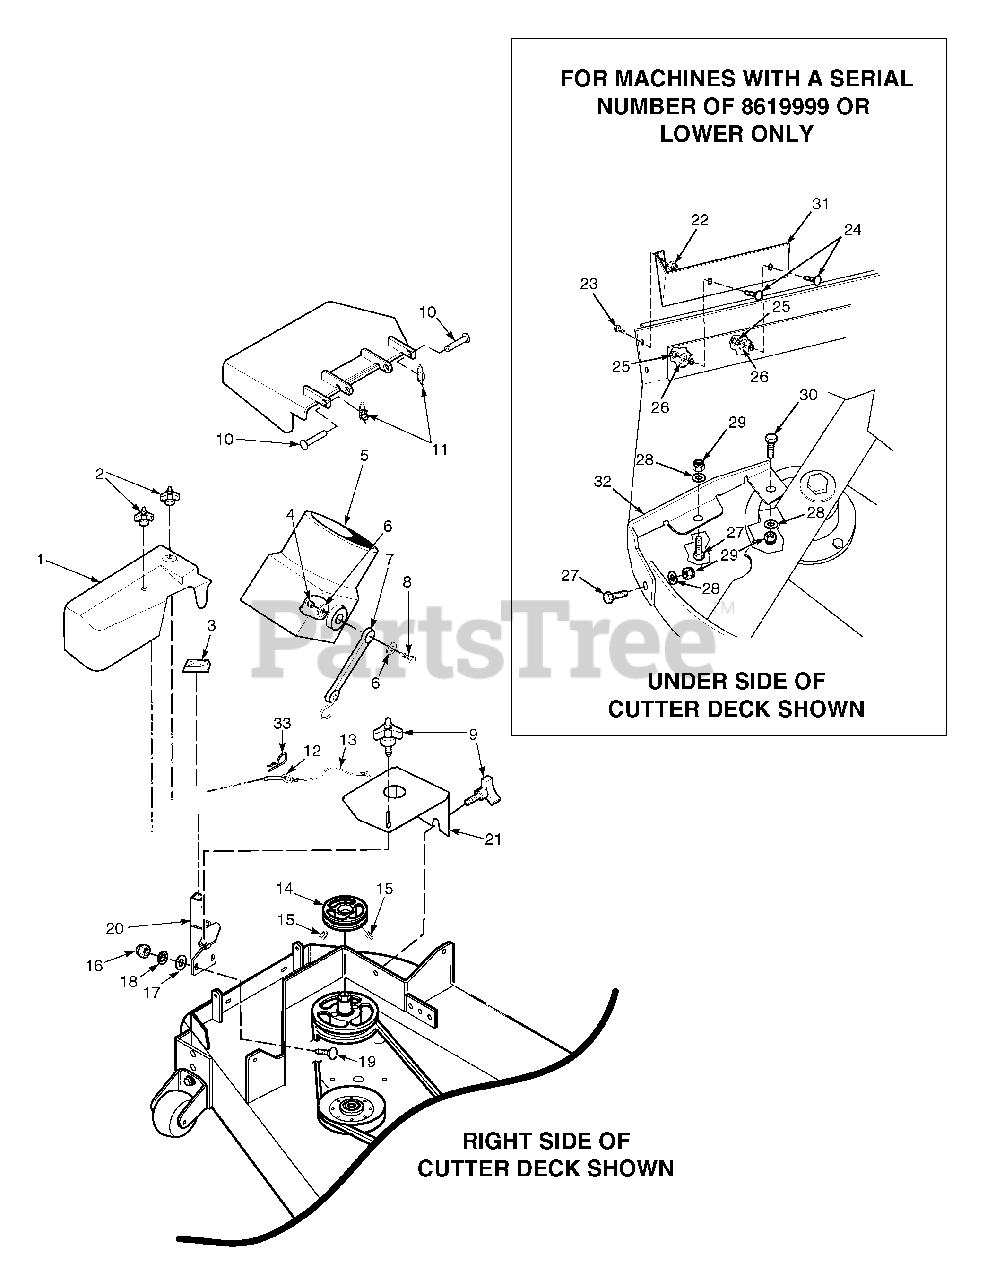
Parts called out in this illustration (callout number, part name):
1	Belt Cover, GC-STT - 52"
2	Wingnut, Plastic 3/8 Small
3	Cap, Square Vinyl
4	Nut, Elastic Stop 1/4-20
5	Adapter w/Strap
6	Flatwasher, 1/4-.312 x .750 x .065
7	Rubber Strap 7-3/4"
8	Bolt, Hex Head 1/4-20 x 1-1/4"
9	Knob W/Stud, 3/8-16 x 1-1/4"
10	Clevis Pin, 5/16 x 1-1/2"
11	Pin, Rue Cotter 5/16 Dia.
12	Pin, Ring 1/2 x 2-1/4"
13	Lanyard
14	Pulley, 4-1/2" for 52" Deck
15	Setscrew, 5/16-18 x 3/8"
16	Nut, Elastic Stop 1/2-13
17	Flatwasher, 1/2-.531 x 1.062 x .095
18	Lockwasher, 1/2"
19	Bolt, Hex Head 1/2-13 x 1-1/2" Grade 5
20	Mounting Post Weldment, Blower - 52"
21	Belt Cover, - 52"
22	Nut, Serrated Flange 1/4-20
23	Bolt, Hex Head 1/4-20 x 3/4"
24	Bolt, Carriage 3/8-16 x 1"
25	Nut, Elastic Stop 3/8-16
26	Flatwasher, 3/8-.391 x .938 x .105
27	Bolt, Hex Head 5/16-18 x 1"
28	Flatwasher, 5/16-.375 x .875 x .083
29	Nut, Elastic Stop 5/16-18
30	Bolt, Hex Head 5/16-18 x 1-3/4"
31	Baffle, 52"
32	Baffle, 52" Deck
33	Hair Pin Cotter, .177 x 3-1/4"
